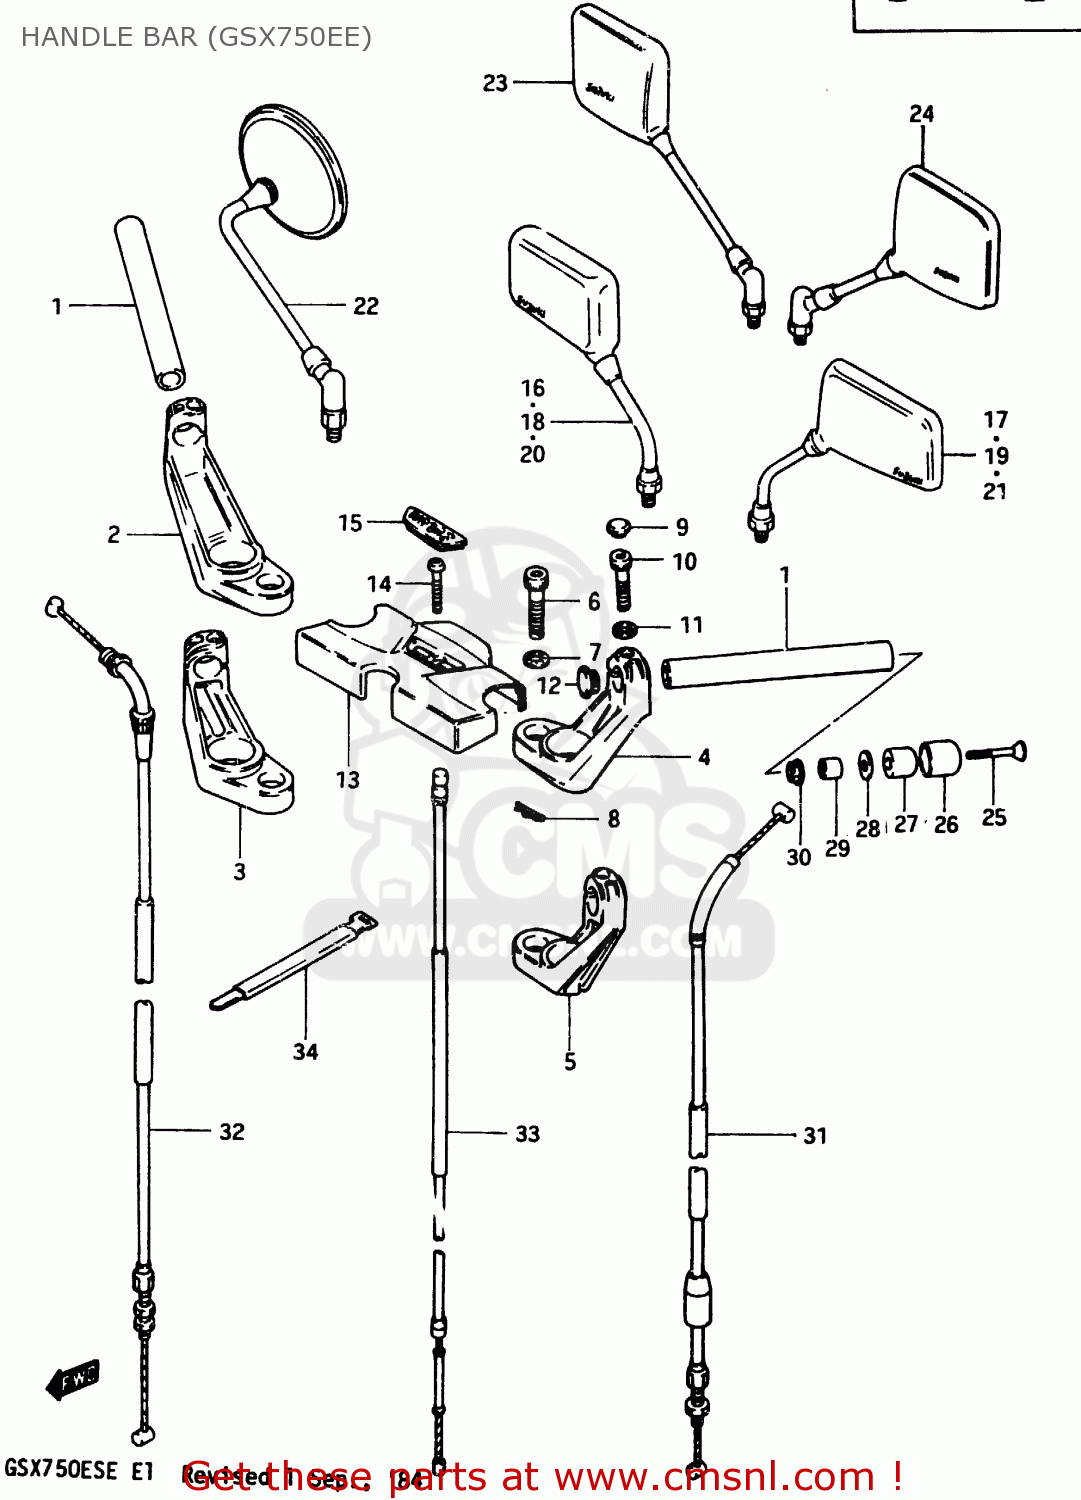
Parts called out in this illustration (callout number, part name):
1	HANDLEBAR
2	HOLDER,HANDLEBAR,RIGHT
3	HOLDER,HANDLEBAR,RIGHT
4	HOLDER,HANDLEBAR,LEFT
5	HOLDER,HANDLEBAR,LEFT
6	BOLT 10X50
7	WASHER
8	CLIP
9	CAP(OD:14.5)
10	BOLT 8X35
11	WASHER
12	CAP,GRIP END
13	PAD,HANDLE
14	SCREW
15	CAP,HANDLE PAD
16	MIRROR ASSEMBLY,RIGHT
17	MIRROR ASSEMBLY,REAR VIEW
18	MIRROR, REAR VIEW RH
19	MIRROR, REAR VIEW LH
20	MIRROR, REAR VIEW RH
21	MIRROR, REAR VIEW LH
22	MIRROR, REAR VIEW
23	MIRROR ASSEMBLY,REAR VIEW
24	MIRROR ASSEMBLY,REAR VIEW
25	SCREW 6X65
26	CAP,BALANCER
27	BALANCER,HANDLE
28	SPACER,BALANCER
29	EXPANDER,BALANCER
30	NUT
31	CABLE ASSY,CLUTCH
32	CABLE ASSY,THROTTLE
33	CABLE COMP,STARTER
34	CLAMP
